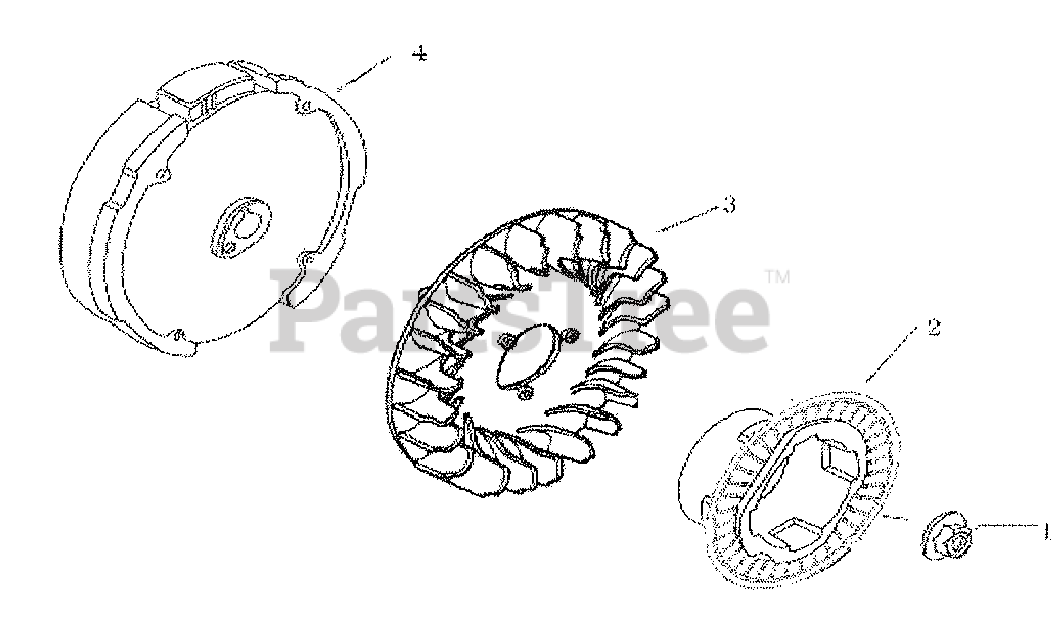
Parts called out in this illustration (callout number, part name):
1	NUT, SPECIAL M14 X 1.5
2	STARTING CUP
3	FAN, COOLING
4	FLYWHEEL COMP
